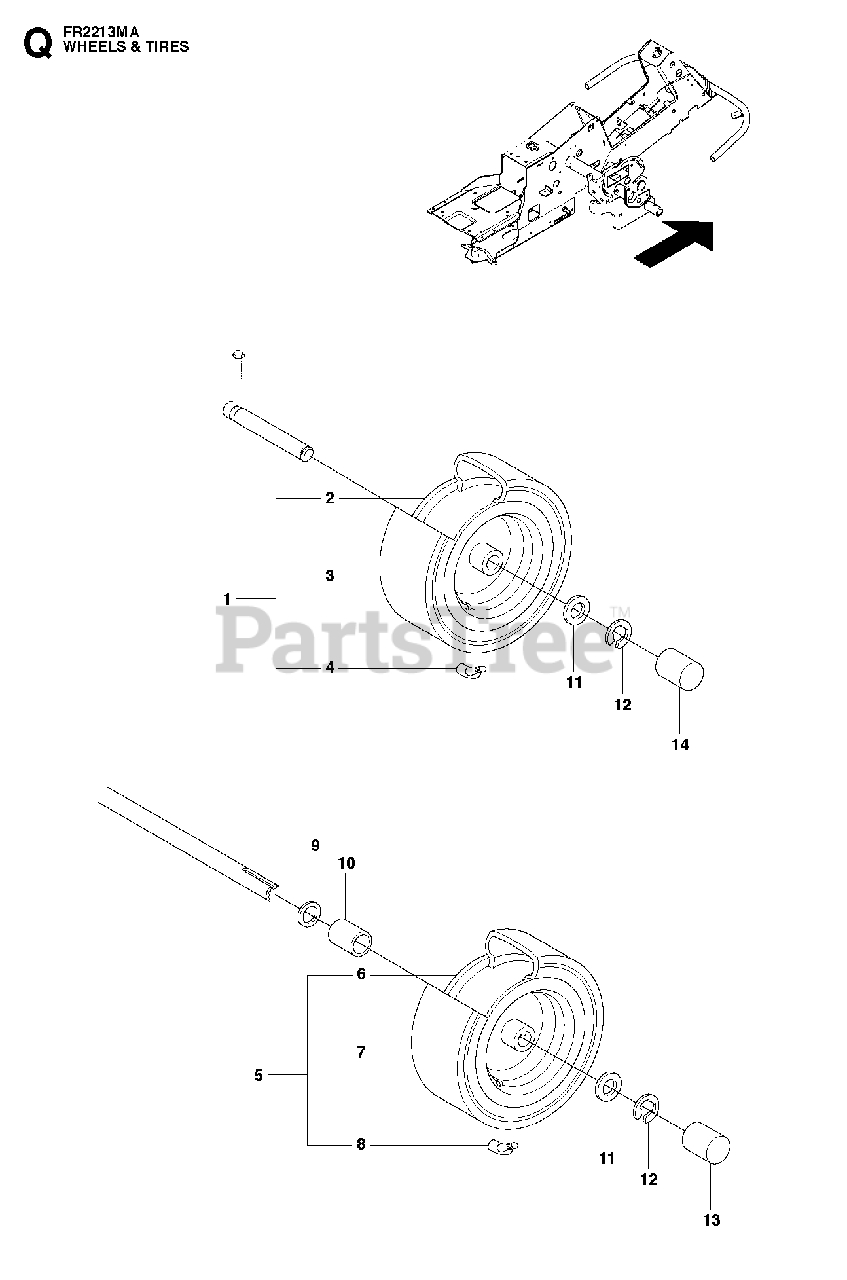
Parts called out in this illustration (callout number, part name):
10	SPACE SLEEVE
12	RETAINING RING
13	DUST CAP
